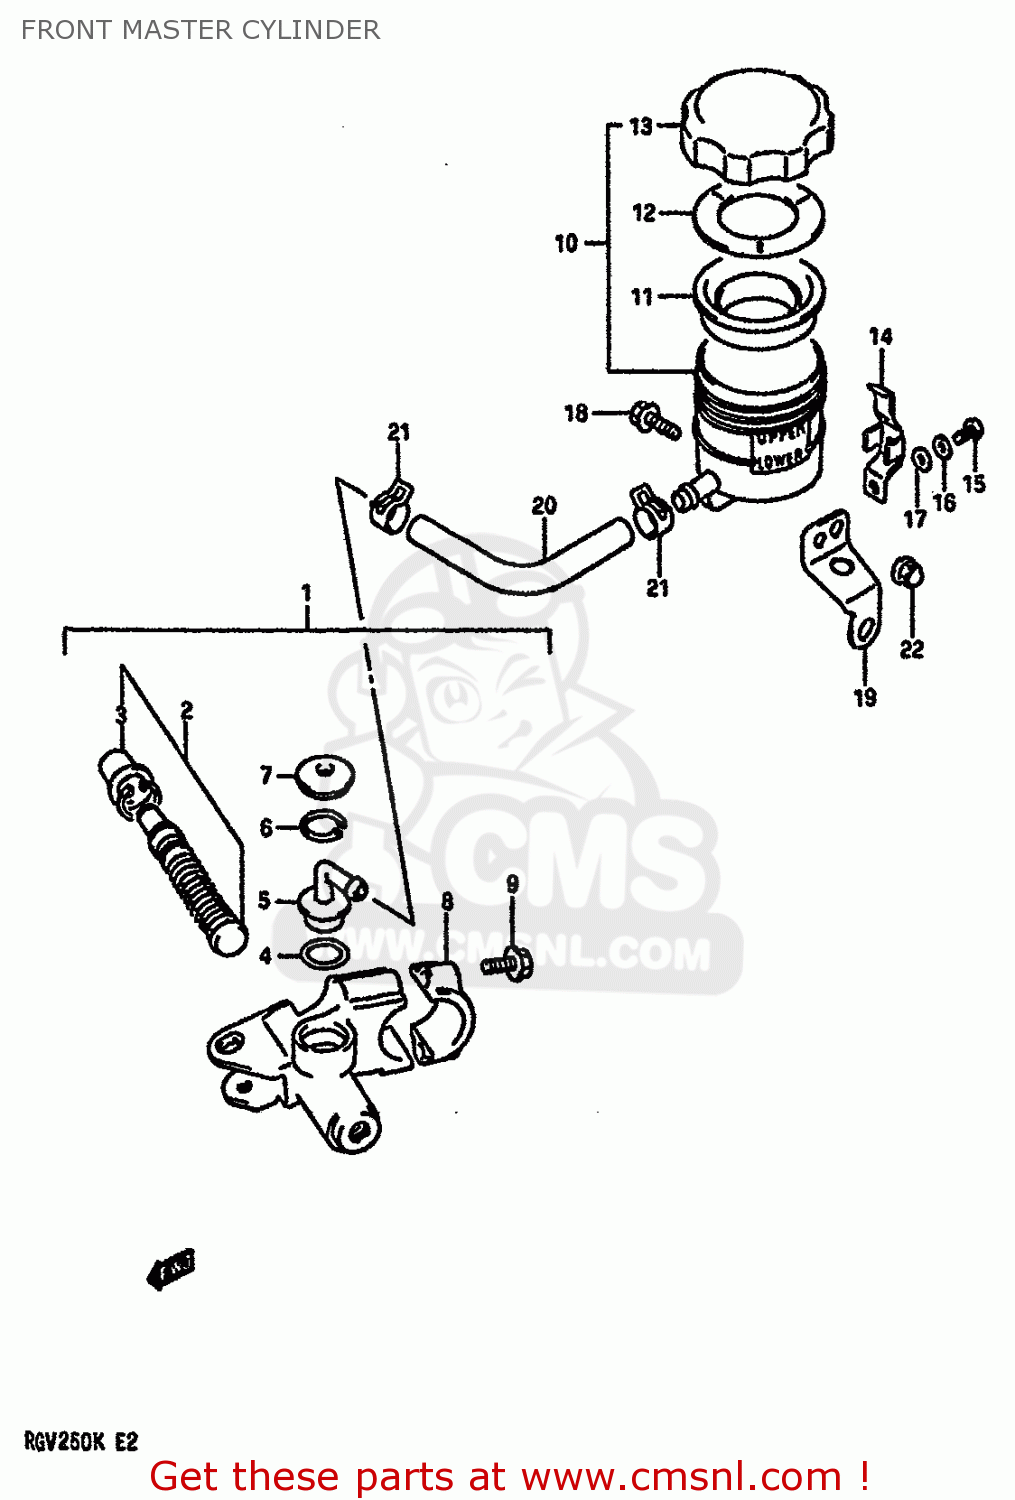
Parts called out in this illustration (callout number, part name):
1	CYLINDER ASSEMBLY,FRONT MASTER
2	PISTON & CUP SET
3	BOOT
4	O RING
5	CONNECTOR
6	CIRCLIP
7	COVER,DUST
8	HOLDER
9	BOLT
10	TANK ASSY,RESERVOIR
11	DIAPHRAGM
12	PLATE,DIAPHRAGM
13	CAP
14	PLATE,RESERVOIR TANK CAP
15	SCREW
16	WASHER,LOCK 4M
17	WASHER 4MM
18	BOLT 6X16
19	BRACKET,FRONT RESERVER TANK
20	HOSE,FR RESERVOIR TANK
21	CLAMP,RESERVOIR TANK FR
22	NUT
